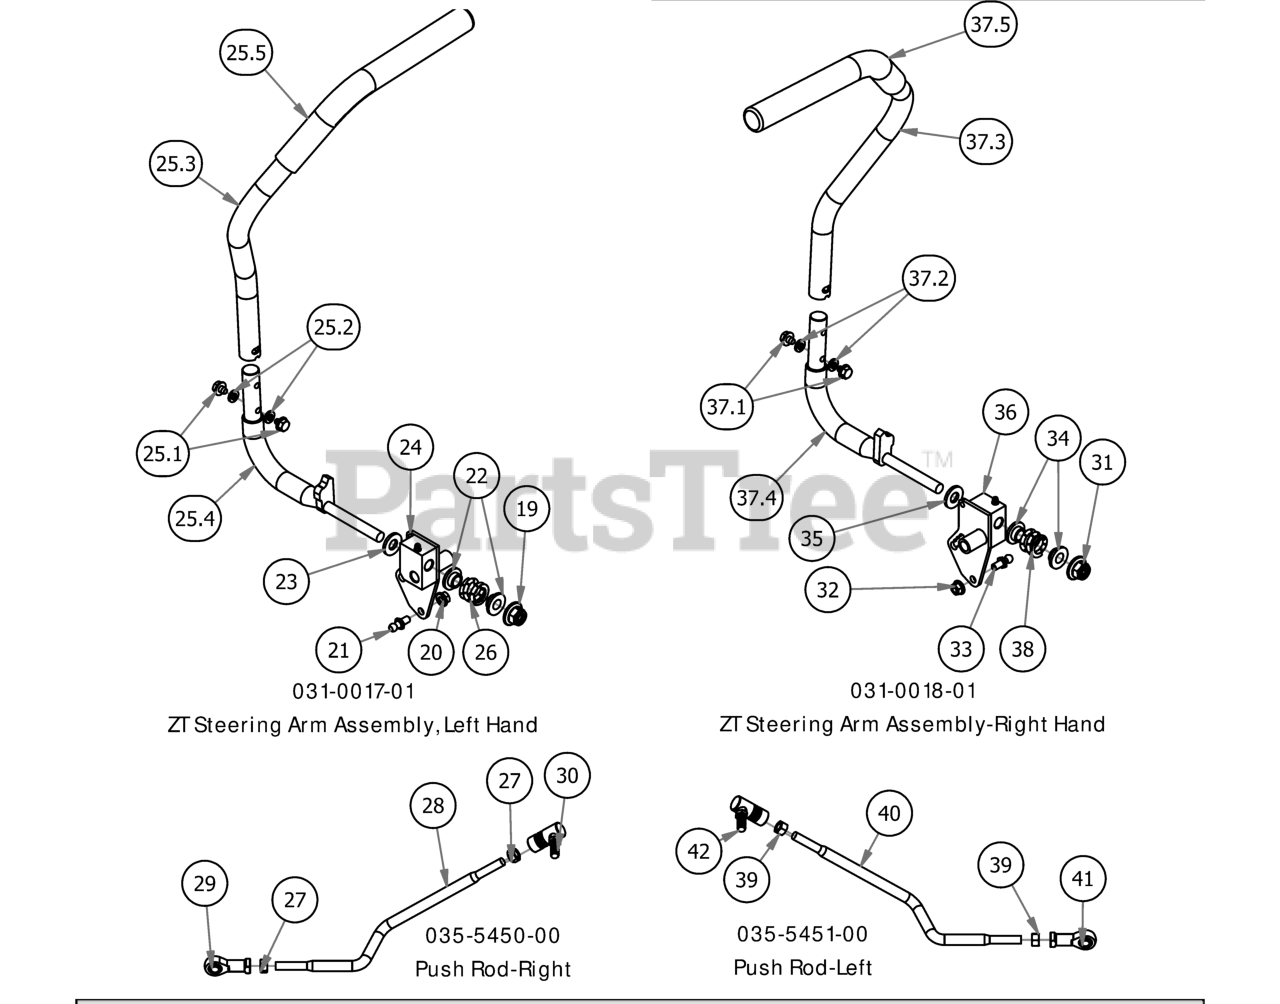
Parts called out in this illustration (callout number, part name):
19	1/2-13 Nylon Flange Nut
20	5/16" Flange Nut
21	10mm Damper Ball Stud-Steering
22	.515 ID Nylon Shoulder Washer
23	.505 Nylon Spacer
24	2017 Drive Lever Housing - Left
25	ZT Steering Arm-Left
25.1	5/16-18 1/2 HWH Bolt-Steering
25.2	5/16" Lock Washer
25.3	ZT Direction Steering Arm (Left)
25.4	Stering Arm Elbow (Left)
25.5	Rubber Grip
26	Drive Lever Spring
27	3/8" Fine Threaded Jam Nut
28	Push Rod - Right
29	Spherical Rod End - Outlaw
30	Quick Release Ball Joint
31	1/2-13 Nylon Flange Nut
32	5/16" Flange Nut
33	10mm Damper Ball Stud-Steering
34	.515 ID Nylon Shoulder Washer
35	.505 Nylon Spacer
36	2017 Drive Lever Housing - Right
37	ZT Steering Arm-Right
37.1	5/16-18 1/2 HWH Bolt-Steering
37.2	5/16" Lock Washer
37.3	ZT Direction Steering Arm (Right)
37.4	Stering Arm Elbow (Right)
37.5	Rubber Grip
38	Drive Lever Spring
39	3/8" Fine Threaded Jam Nut
40	Push Rod - Left
41	Spherical Rod End - Outlaw
42	Quick Release Ball Joint
